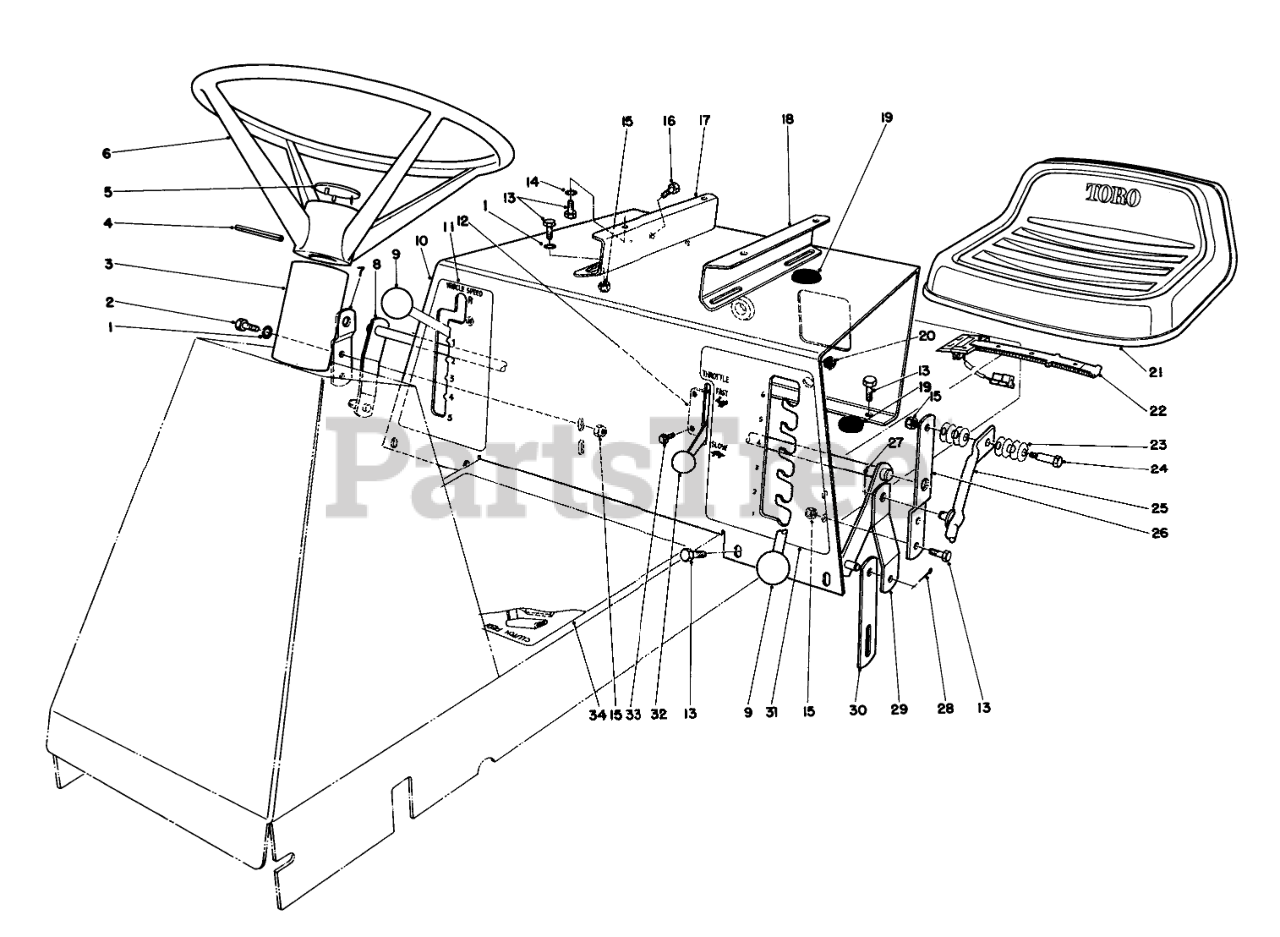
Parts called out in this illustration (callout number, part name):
1	WASHER-PLAIN
2	SCREW-HH
3	STRG. SHAFT COVER
4	PIN-ROLL
5	Cap-Steering Wheel
6	Wheel-Steering (Incl. Ref. #5)
7	Bracket H.O.C Support
8	HOC LEVER WA B
10	Support Seat
11	Decal-Transmission
12	Throttle Control (Incl. Ref. #32)
13	SCREW-HH
14	WASHER-LOCK
15	NUT-LOCK, NI
16	SCREW-HH
17	Bracket-Seat RH.
18	Bracket-Seat LH.
19	GROMMET
20	GROMMET
21	Seat
22	SWITCH-SEAT
23	WASHER-BELLEVILLE
24	BOLT-SHOULDER
25	HOC LEVER WA B
26	Bracket
27	PIN-COTTER
28	PIN-COTTER
29	Bracket-Height Of Cut Engagement
30	Link-Deck Suspension
31	Decal-Height Of Cut
32	KNOB-CONTROL
33	SCREW-HWHTF
34	INSTRUCTION DECAL
